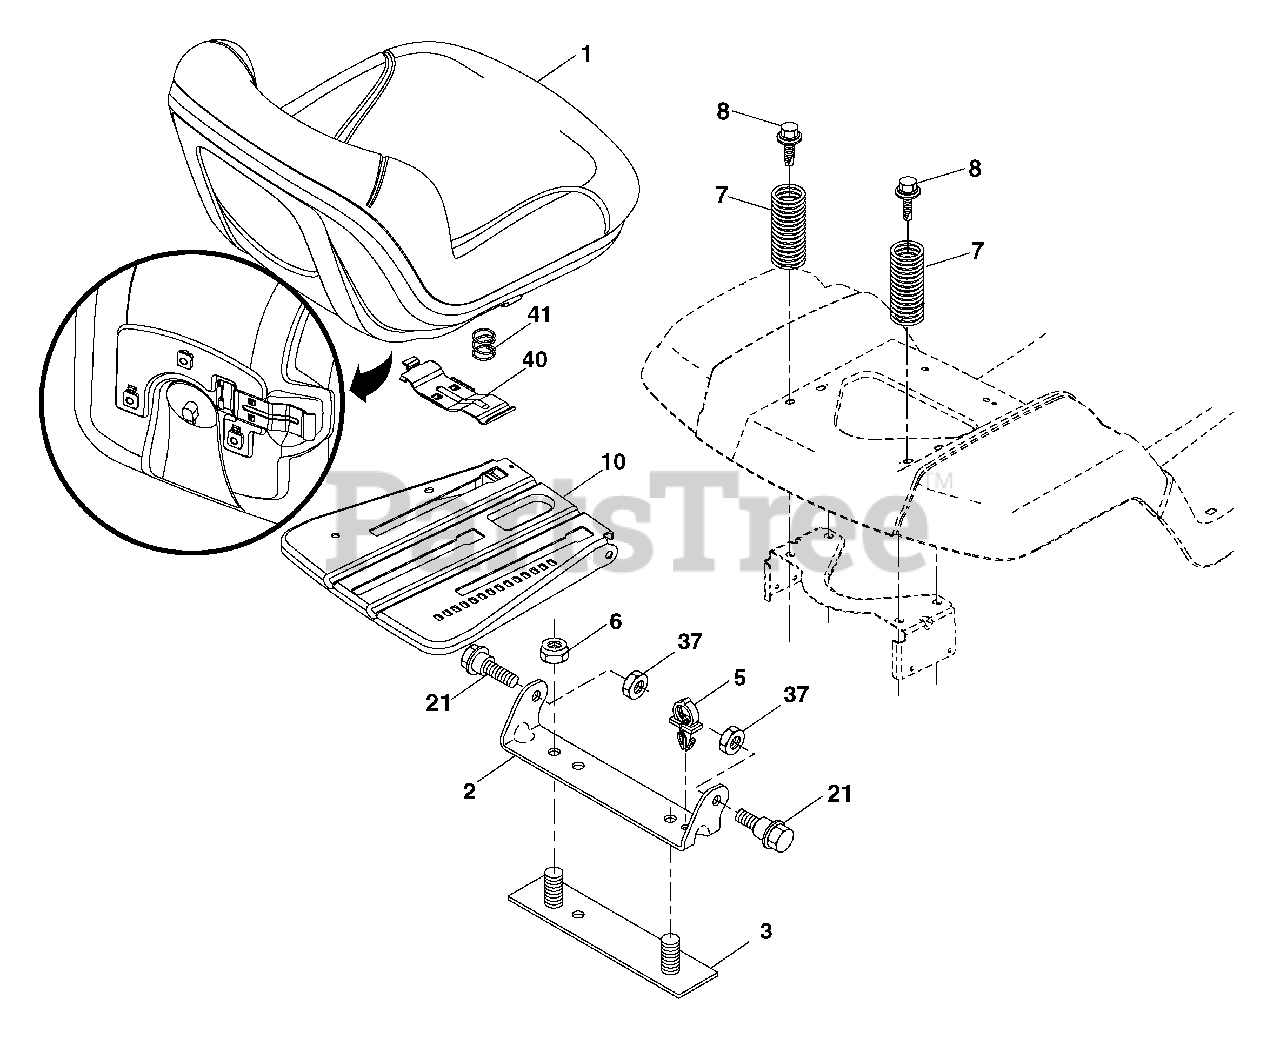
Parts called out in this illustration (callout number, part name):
1	Seat
2	Bracket Pivot Fender
3	Strap, Asm Fender
5	Clip, Push In, Hinged
6	Nut, Lock W/Ins. 3/8-16 unc
7	Spring, Seat Cprsn
8	Bolt 5/16-18 uncx 3/4 w/Sems
10	Pan, Seat
21	Bolt, Shoulder 5/16-18
37	Nut, Lock 5/16-18 unc
40	Handle Slide Seat
41	Spring Latch Seat
43	Bolt 3/8-16 x 3/4
44	Washer 13/32 x 2-3/8 x 12 Ga.
